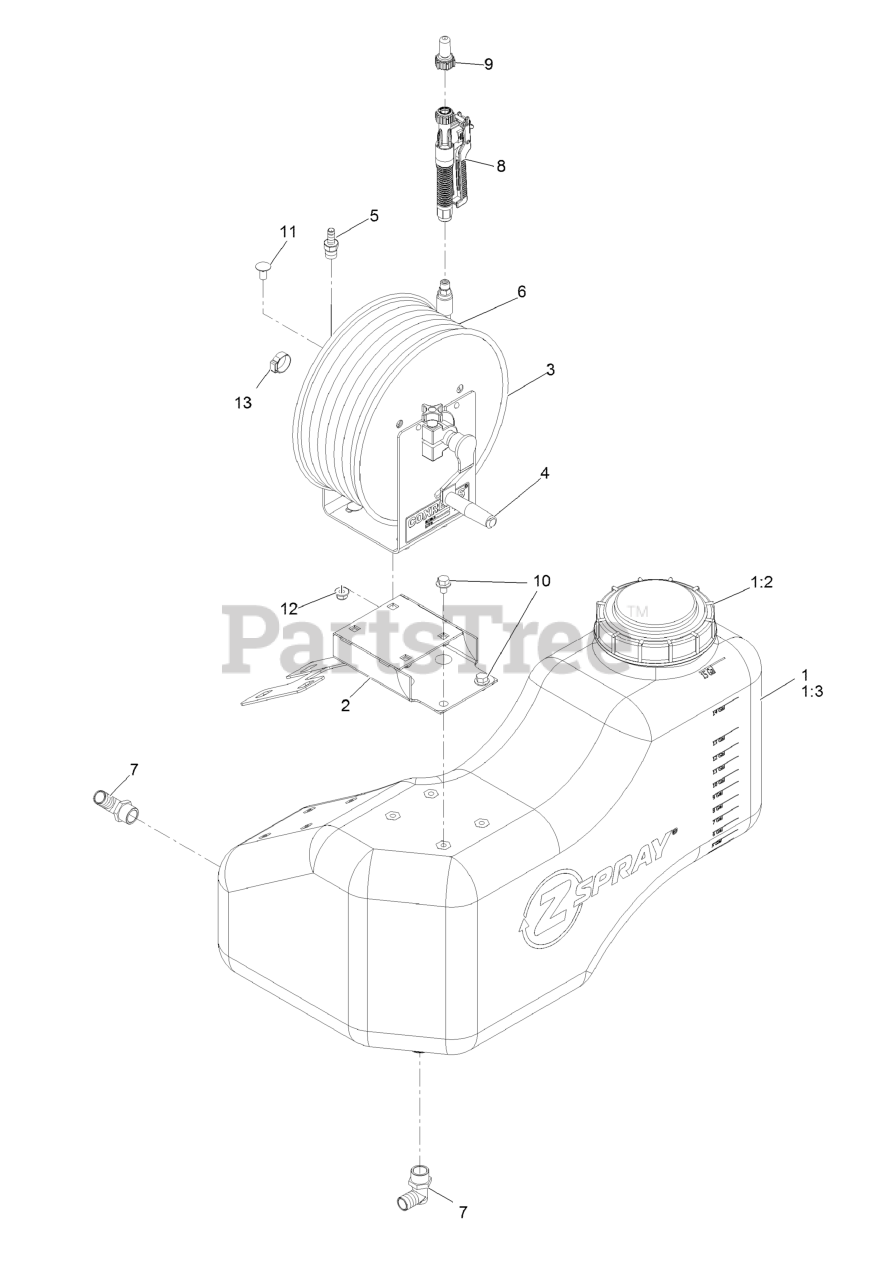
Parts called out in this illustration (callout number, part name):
1	ASM-TANK, LT
1:2	CAP-TANK, SPRAY
1:3	FITTING-BULKHEAD
2	MOUNT-REEL, HOSE
3	REEL-HOSE
4	Crank-Reel
5	FITTING,MALE
6	HOSE-SPRAY, 75'
7	FITTING-ELBOW, 90
8	GUN-SPRAY, SPOT
9	TIP-SPRAY, #12 SPOT
10	Screw-HHF
11	SCREW-CARRIAGE
12	Nut-Hex Flange
13	CLAMP-OETIKER, 167
